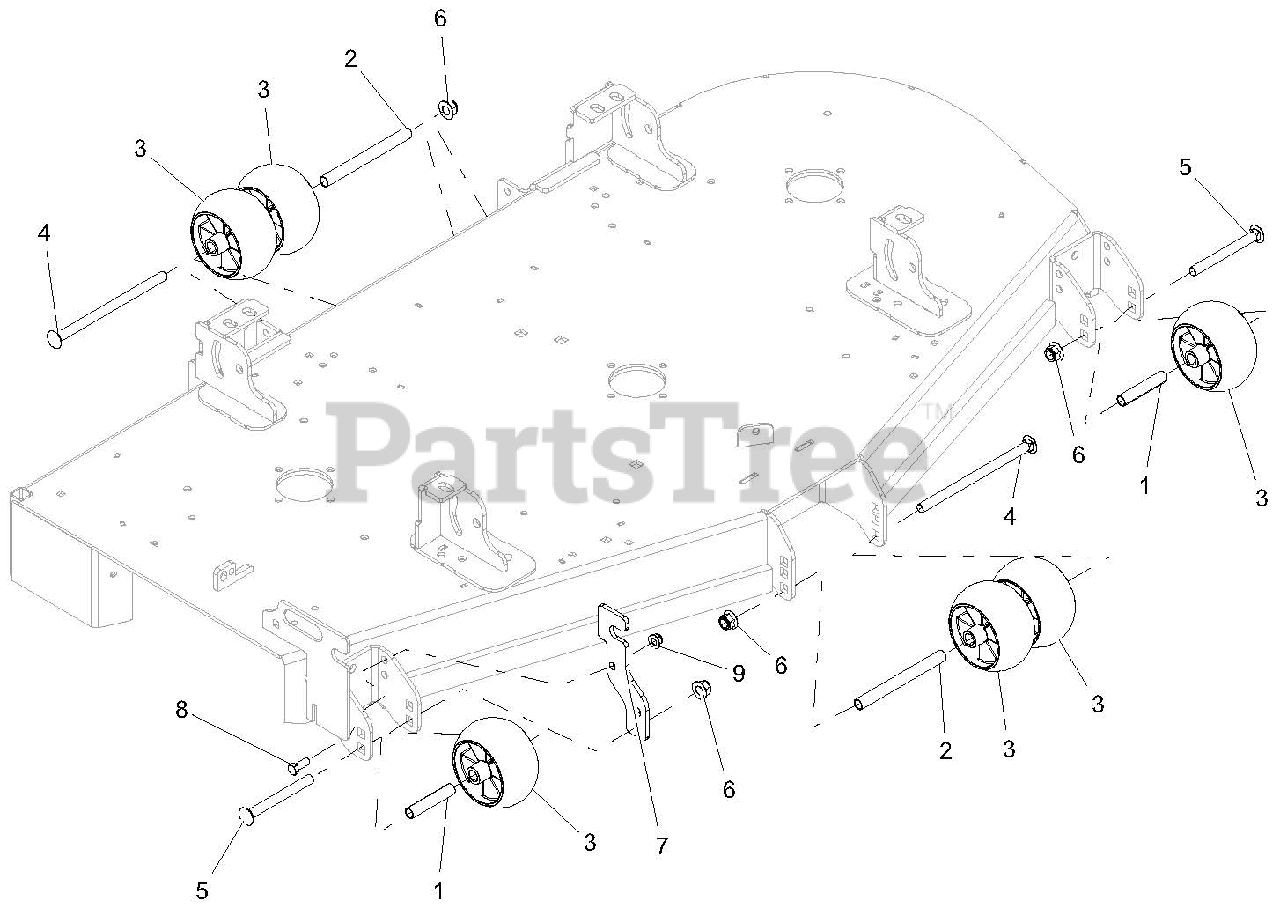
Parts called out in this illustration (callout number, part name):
1	SPACER, .510X.625X3.35
2	SPACER, .510 X .625 X 6.50
3	ANTI-SCALP WHEEL - 5X3 CTR
4	BLT-RDHDSQNK .50-13X8.50 Y
5	BLT-RDHDSQNK .50-13X5.00 G5 YWZC
6	NUT-LK-NYL-FLG .50-13 YWZC
7	CHUTE STORAGE BRACKET-RED
8	BLT-HEX .38-16X1.00 GR5 YWZC
9	NUT-LK-NYL-FLG .38-16 YWZC
